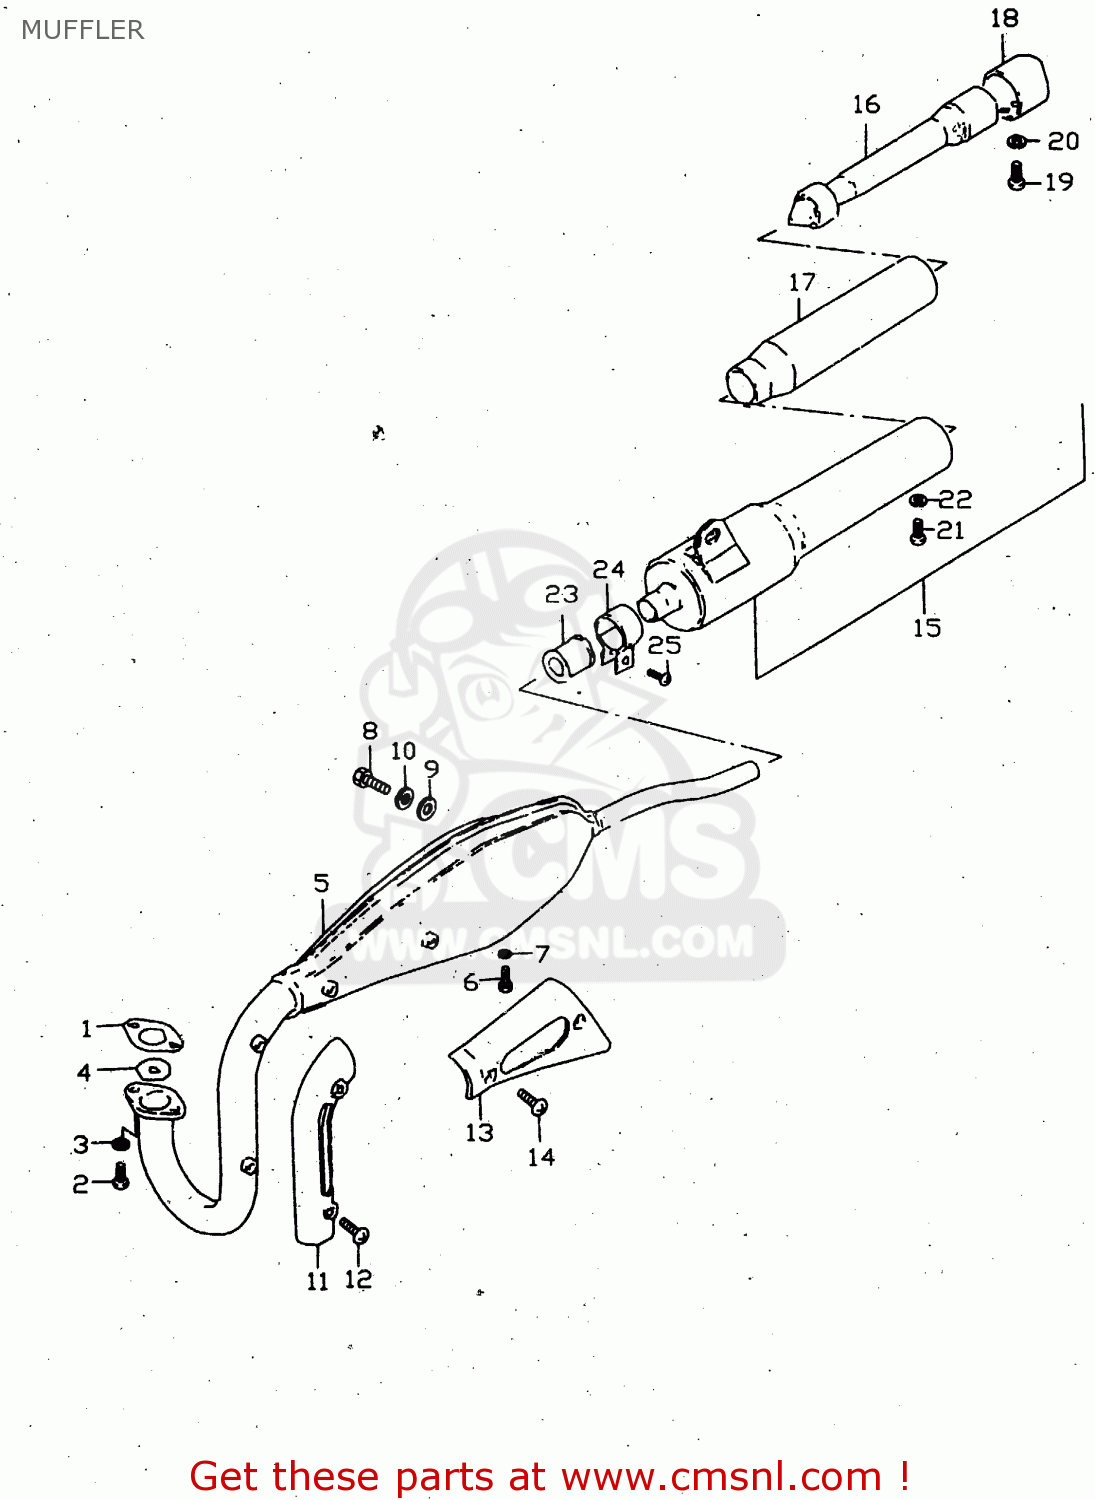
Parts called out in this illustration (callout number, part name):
1	GASKET,EXHAUST PIPE (NAS)
2	BOLT,OIL FILLE
3	LOCK WASHER
4	PLATE,EXHAUST PIPE
5	MUFFLER ASSY
6	BOLT
7	WASHER
8	BOLT
9	WASHER (8.2X20X1.6)
10	LOCK WASHER
11	COVER,EXHAUST PIPE
12	SCREW (M5X6)
13	COVER,MUFFLER
14	SCREW (M5X6)
15	MUFFLER ASSY,2ND
16	TUBE,CLEAN OUT
17	SHELL,ARRESTER
18	CUTTER,MUFFLER TAIL
19	SCREW
20	LOCK WASHER
21	SCREW 6X16
22	LOCK WASHER
23	CONNECTOR,MUFFLER
24	CLAMP
25	SCREW 6X16
